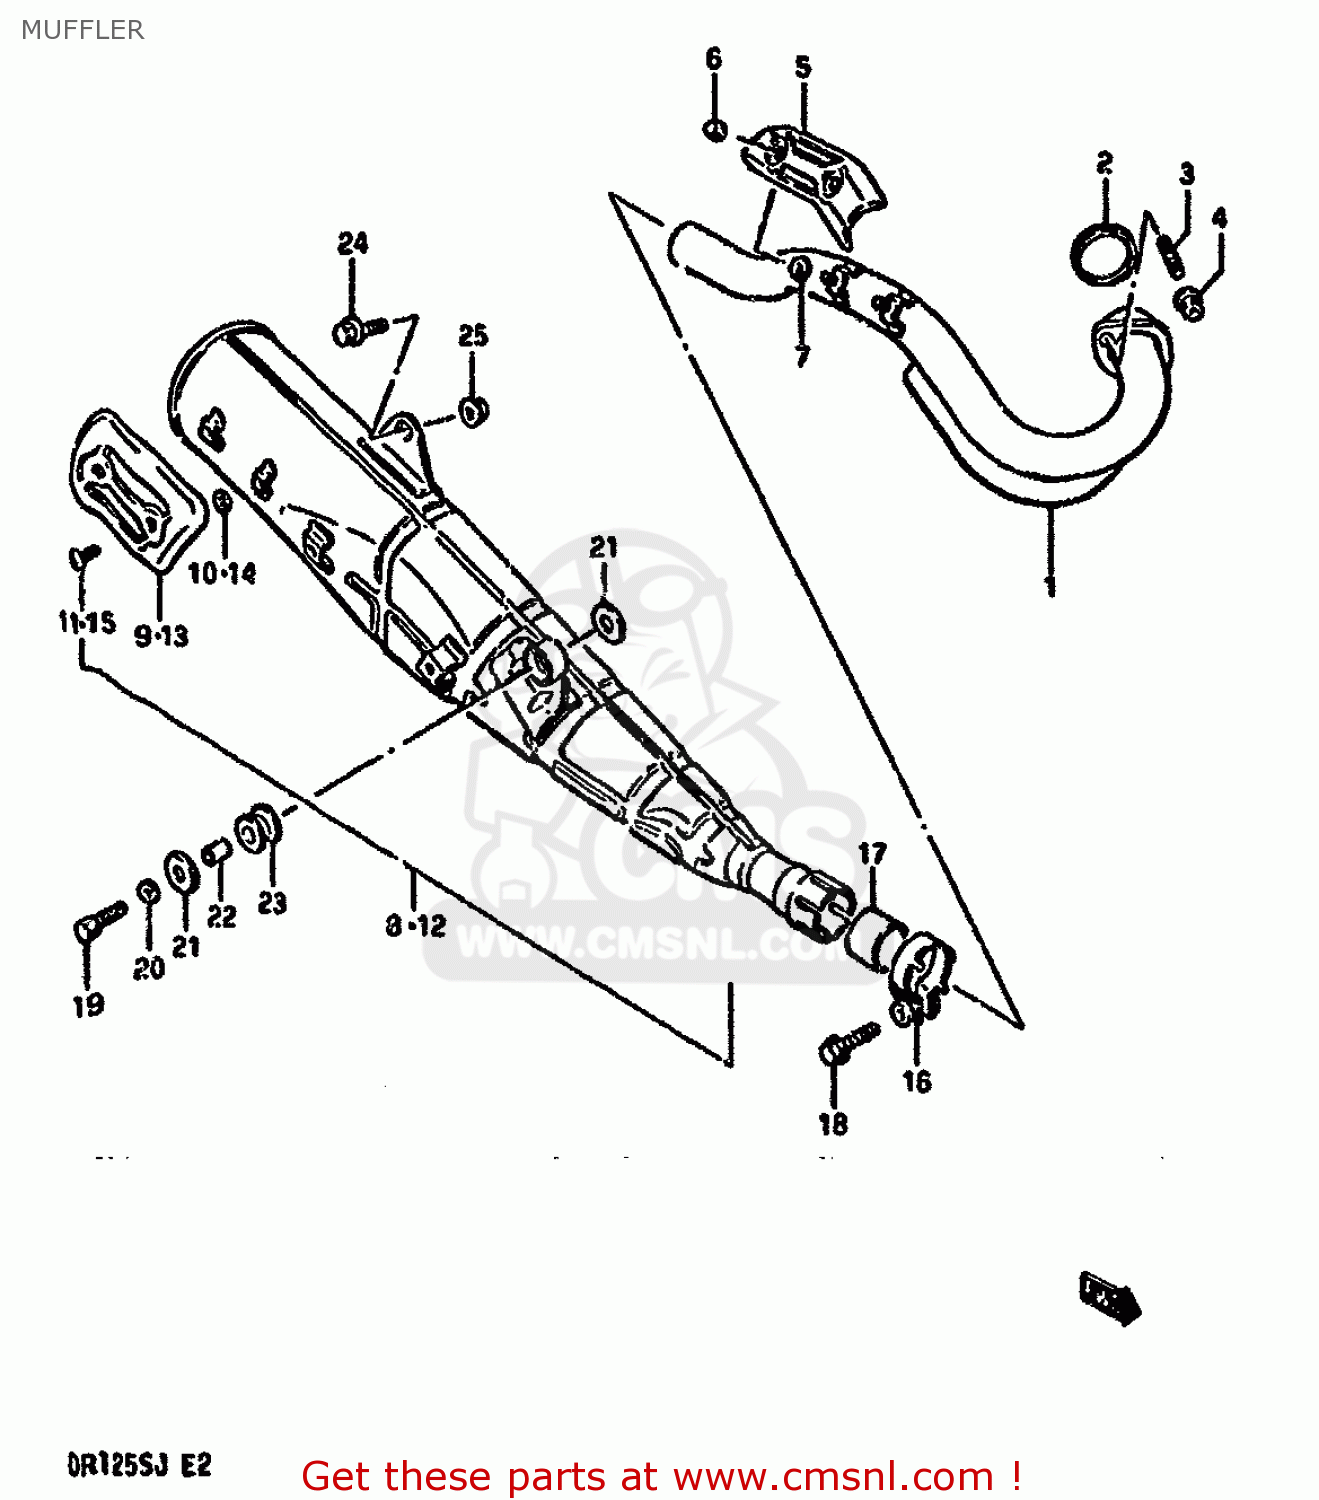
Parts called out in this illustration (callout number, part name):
1	PIPE,EXHAUST
2	GASKET,EXHAUST PIPE (NAS)
3	BOLT,STUD
4	NUT
5	COVER,EXHAUST PIPE
6	NUT (6MM)
7	GASKET (NAS)
8	MUFFLER ASSY
9	COVER
10	GASKET (NAS)
11	SCREW
12	MUFFLER ASSY
13	COVER,MUFFLER
14	GASKET (NAS)
15	SCREW
16	CLAMP,MUFFLER CONNECTOR
17	CONNECTOR,MUFFLER
18	BOLT
19	BOLT
20	LOCK WASHER
21	WASHER (8.5X29X1.6)
22	SPACER (8.6X12X17.5)
23	CUSHION
24	BOLT(8X25)
25	NUT
